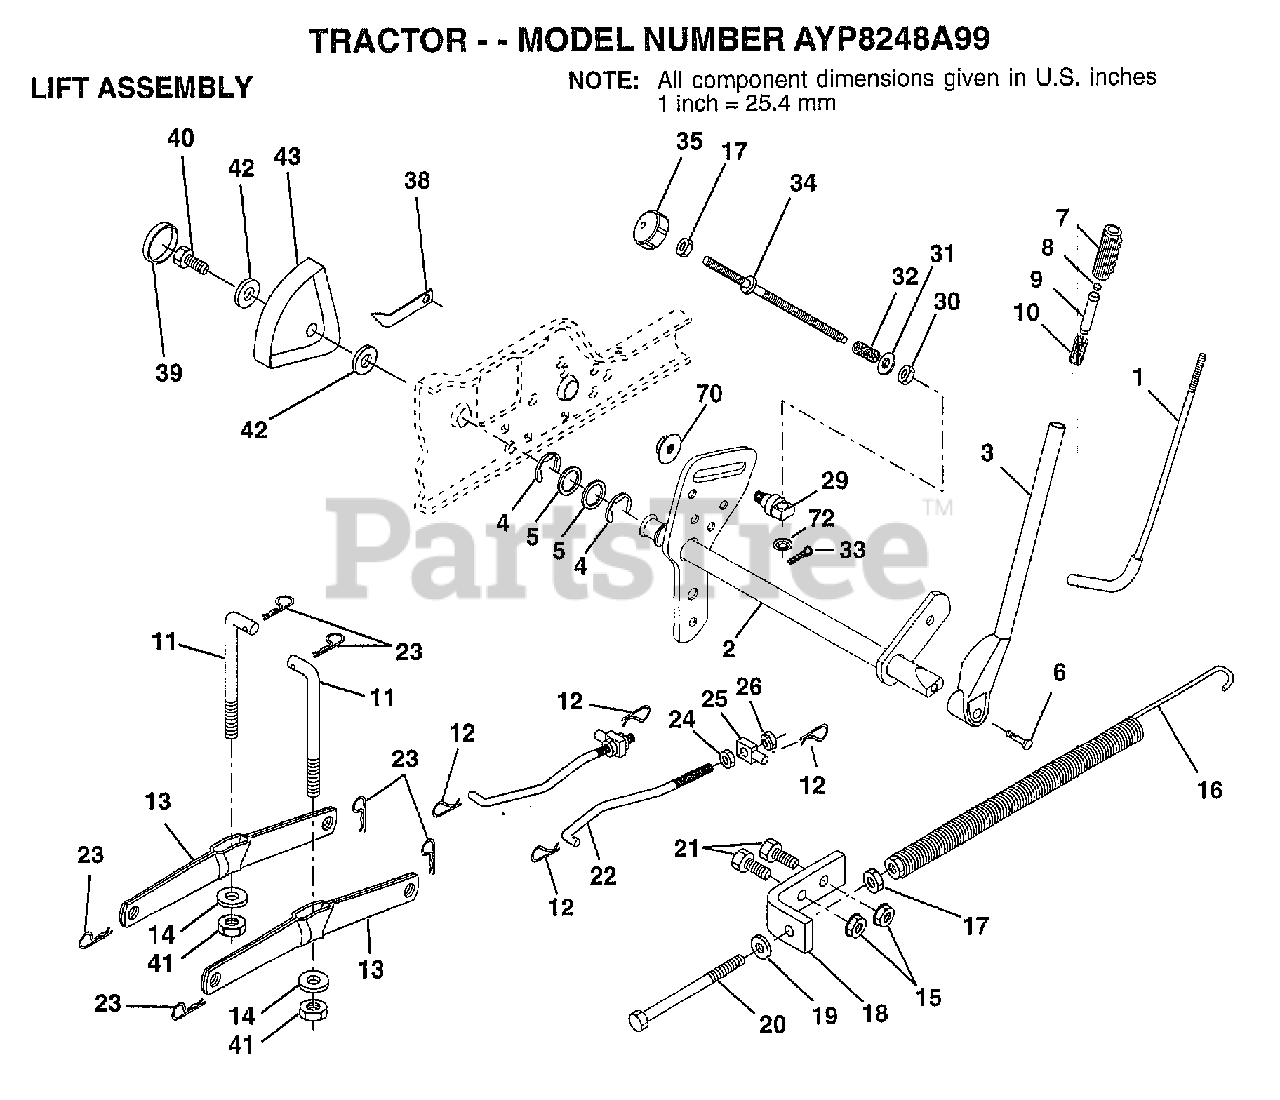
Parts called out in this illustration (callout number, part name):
1	LEVER ROD LT
2	SHAFT.ASM.LIFT.VGT
3	LEVER.ASM.LIFT.RH
4	E-RING
5	WASHER
6	"BOLT,HEX"
7	GRIP HANDLE
10	SPRING T
11	LINK.LIFT.MWR.VGT
12	RETAINER SPRING
13	ARM SUSP REAR
14	BEARING PVT LH
17	NUT
18	BRACKET SPRING AS
19	WASHER
20	BOLT-ADJ SPRING T
21	BOLT
22	LINK.FRONT
24	NUT
25	TRUNION
26	NUT.LK.W/WSH.1/2.
29	TRUNNION
30	NUT T
31	WASHER
32	SPRING.COMP.INF.H
34	ROD.ADJ.LIFT
35	KNOB INF 3/8-16
38	POINTER-INDICAT
39	"PLUG,HOLE"
40	SCREW
41	NUT.CROWNLOCK.3/8
42	WASHER
43	HEIGHT INDICATOR
70	NUT.HXFLG.LOCK.
72	NUT PUSH M
